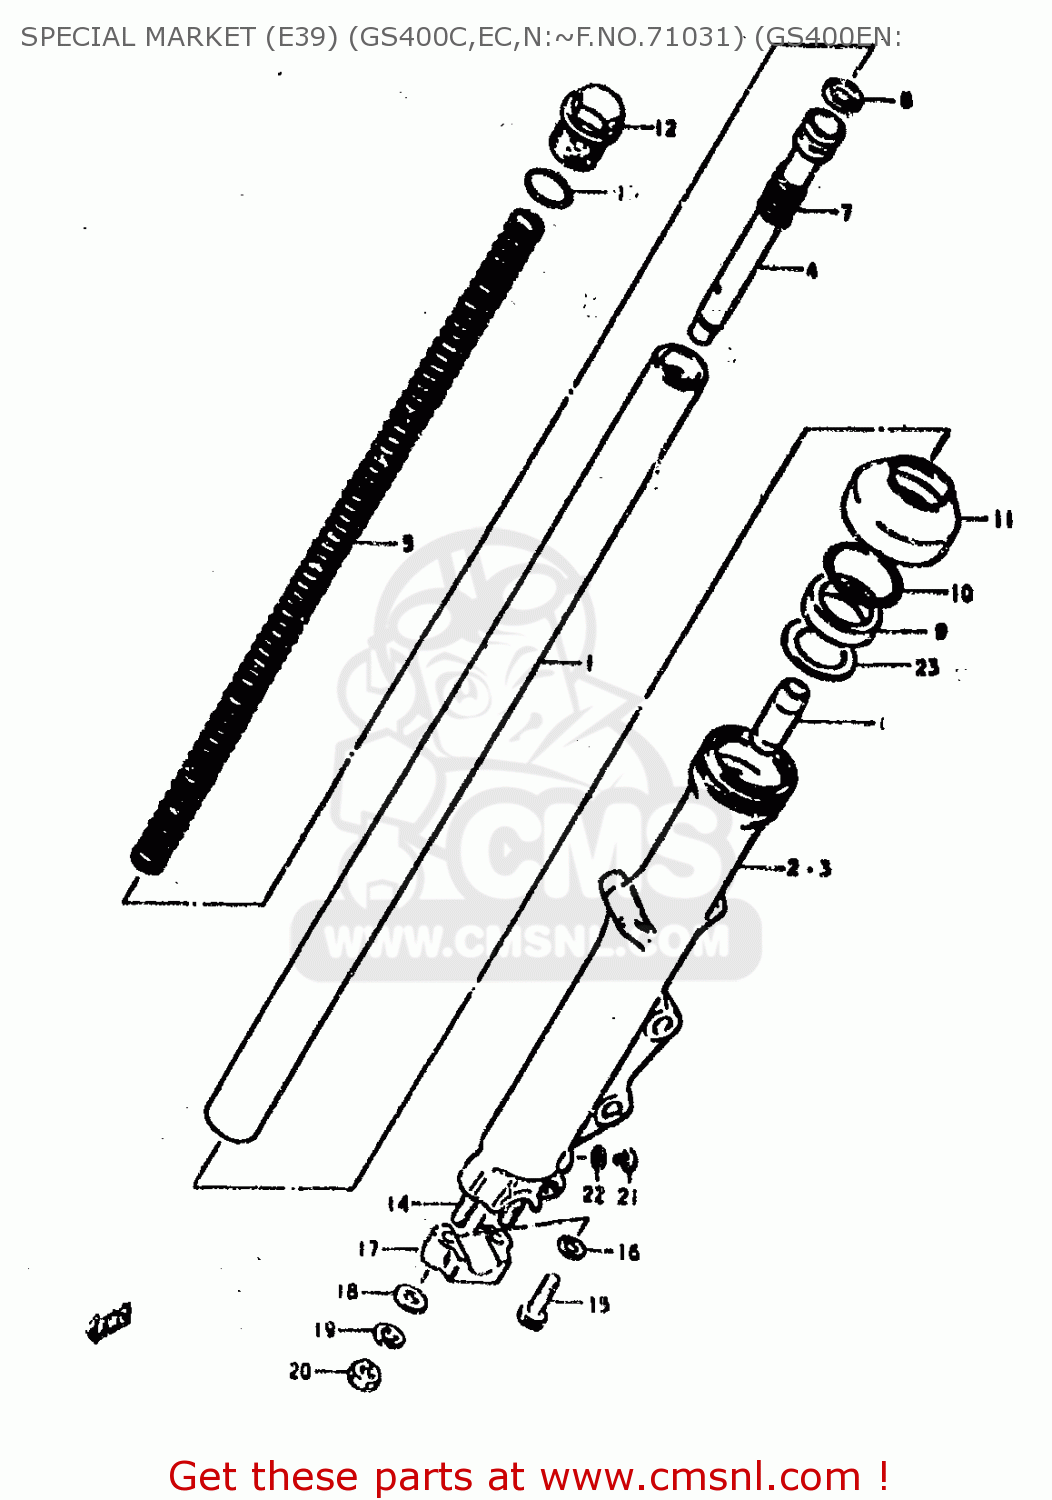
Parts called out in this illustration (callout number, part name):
1	TUBE,INNER
2	TUBE,FORK,LEFT,OUTER
3	TUBE,FORK,OUTER,RIGHT
4	CYLINDER,FRONT FORK
5	SPRING
6	PIECE,OIL LOCK
7	SPRING,REBOUND
8	RING,PISTON
9	OIL SEAL,FRONT FORK
10	CIRCLIP,FORK OIL SEAL
11	BOOT
12	BOLT
13	O RING
14	STUD 8X25
15	BOLT
16	GASKET (NAS)
17	HOLDER,AXLE
18	WASHER
19	LOCK WASHER
20	NUT
21	SCREW
22	GASKET (NAS)
23	SPACER,OIL SEAL
